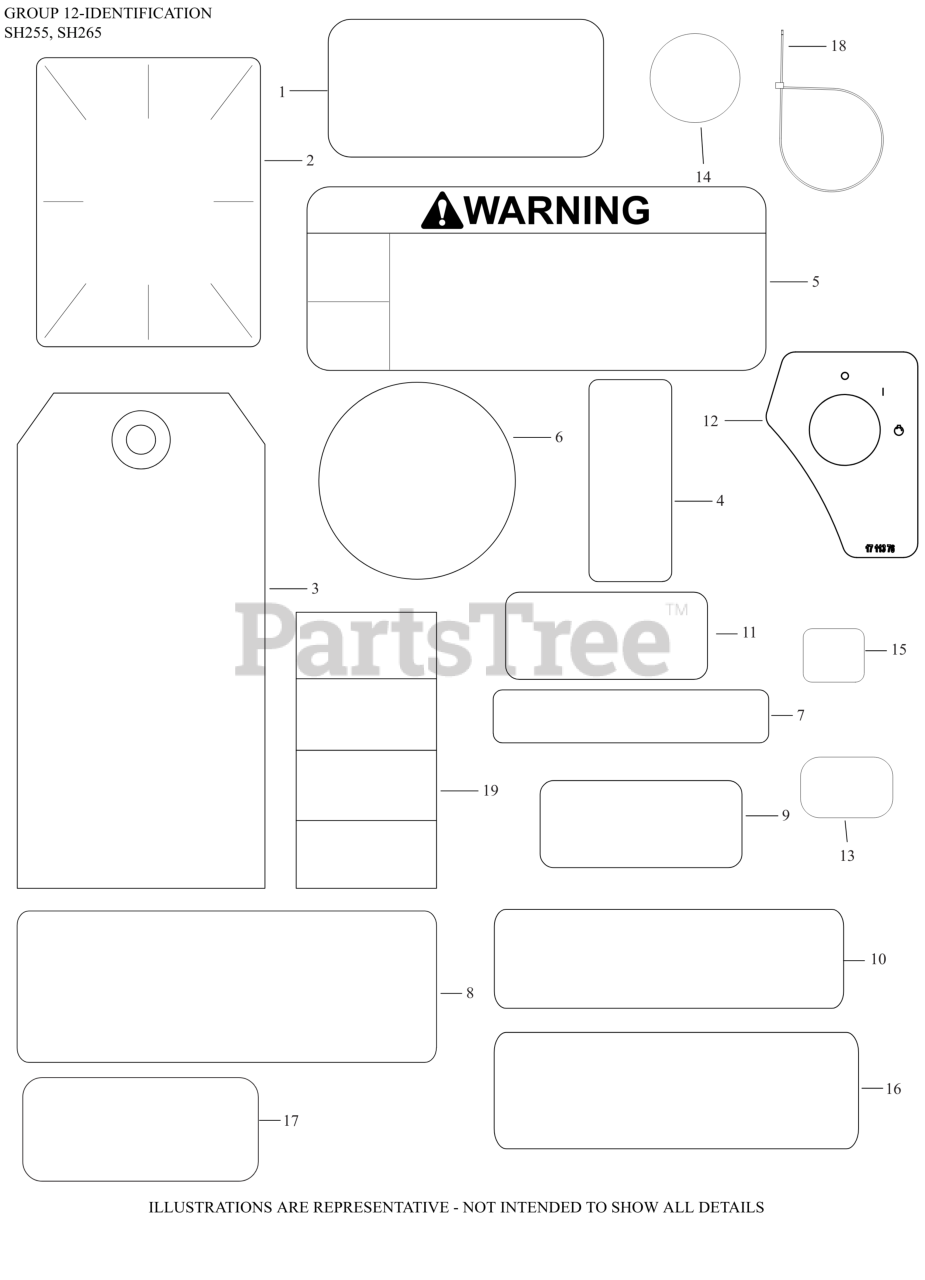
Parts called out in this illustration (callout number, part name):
1	LABEL, MAINTENANCE (CKY)
2	LABEL, CLEAR LAMINATION
3	TAG, HANG
4	DECAL, FUEL/CHOKE - ON/OFF
5	DECAL, WARNING
6	LABEL, RECOIL 75MM
7	DECAL, THROTTLE
8	LABEL, HORSEPOWER
17	DECAL, ETHANOL WARNING
